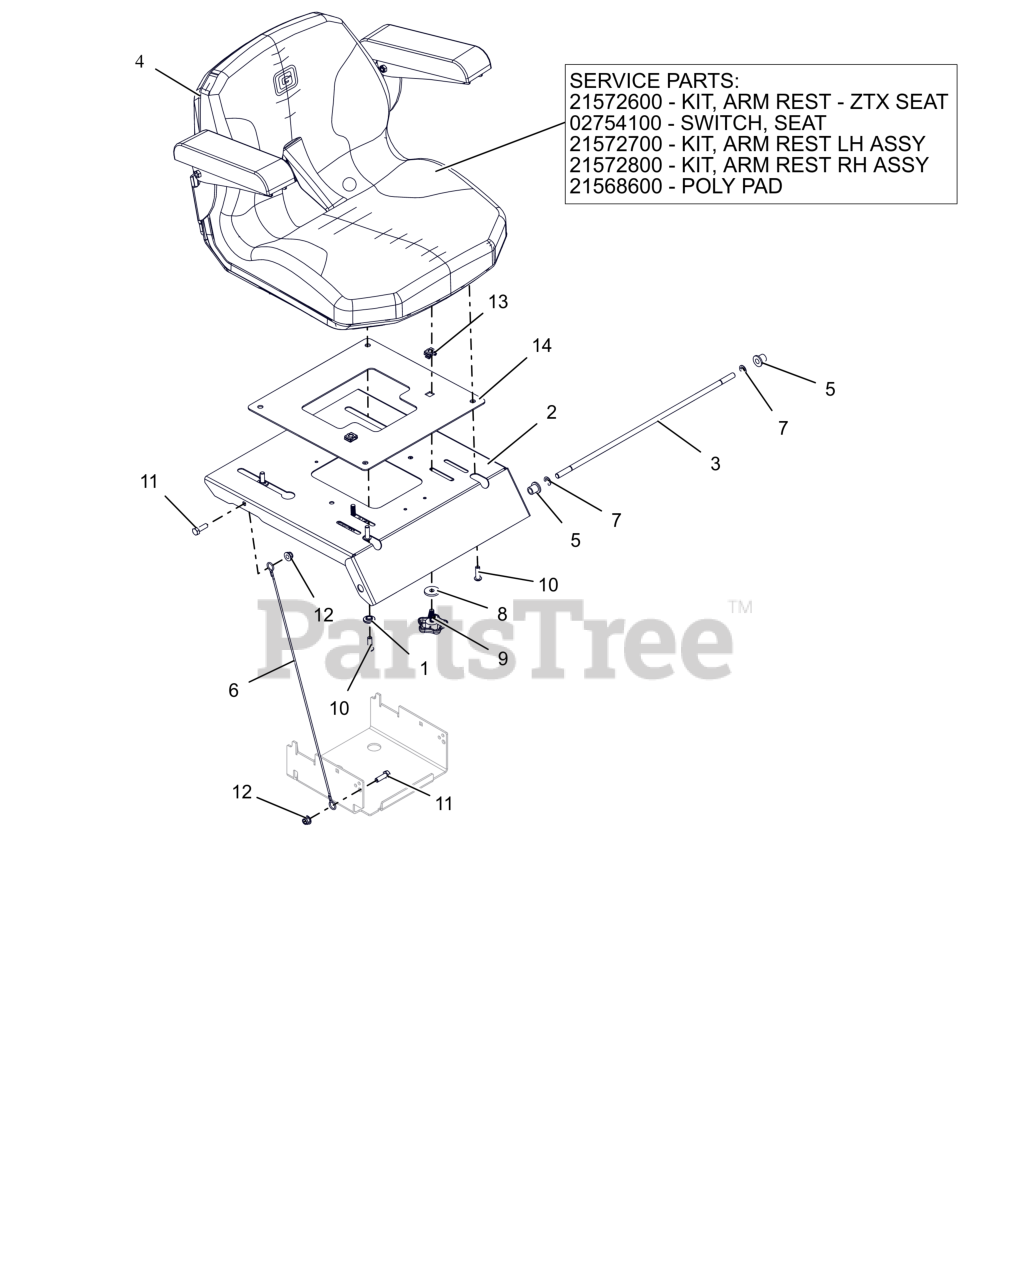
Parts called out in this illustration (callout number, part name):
1	BSHG, FLG .325X.499X.26X.88
2	PLATE, SEAT PLATE (SK100)
3	ROD, SEAT PIVOT
4	SEAT, ZTX 2019-PADDED ARMS
4	KIT, ARM REST-ZTX SEAT PADDED
4	SWITCH- SNAP MTG N.O.
4	KIT, ARM REST LH ASSY-PADDED
4	KIT, ARM REST RH ASSY-PADDED
4	POLY PAD - ZTX SEAT
5	BSHG-FLG .38X.580X.667X.750
6	LANYARD, SEAT CABLE .093X19.5
7	RG-RTNG-EXT .375X.035 TYP E
8	WSHR, FLT .340X1.125X.135 ZCC
9	KNOB, WING STUDDED
10	BLT,SHCS-BTN .31-18X1.00 ZCC
11	BLT,HEX .31-18X1.00 G5 ZCC
12	NUT,NYL-FLG .31-18 GF ZCC
13	NUT, RETNR .312-18
14	PLATE, SEAT ADAPTOR (BLACK)
